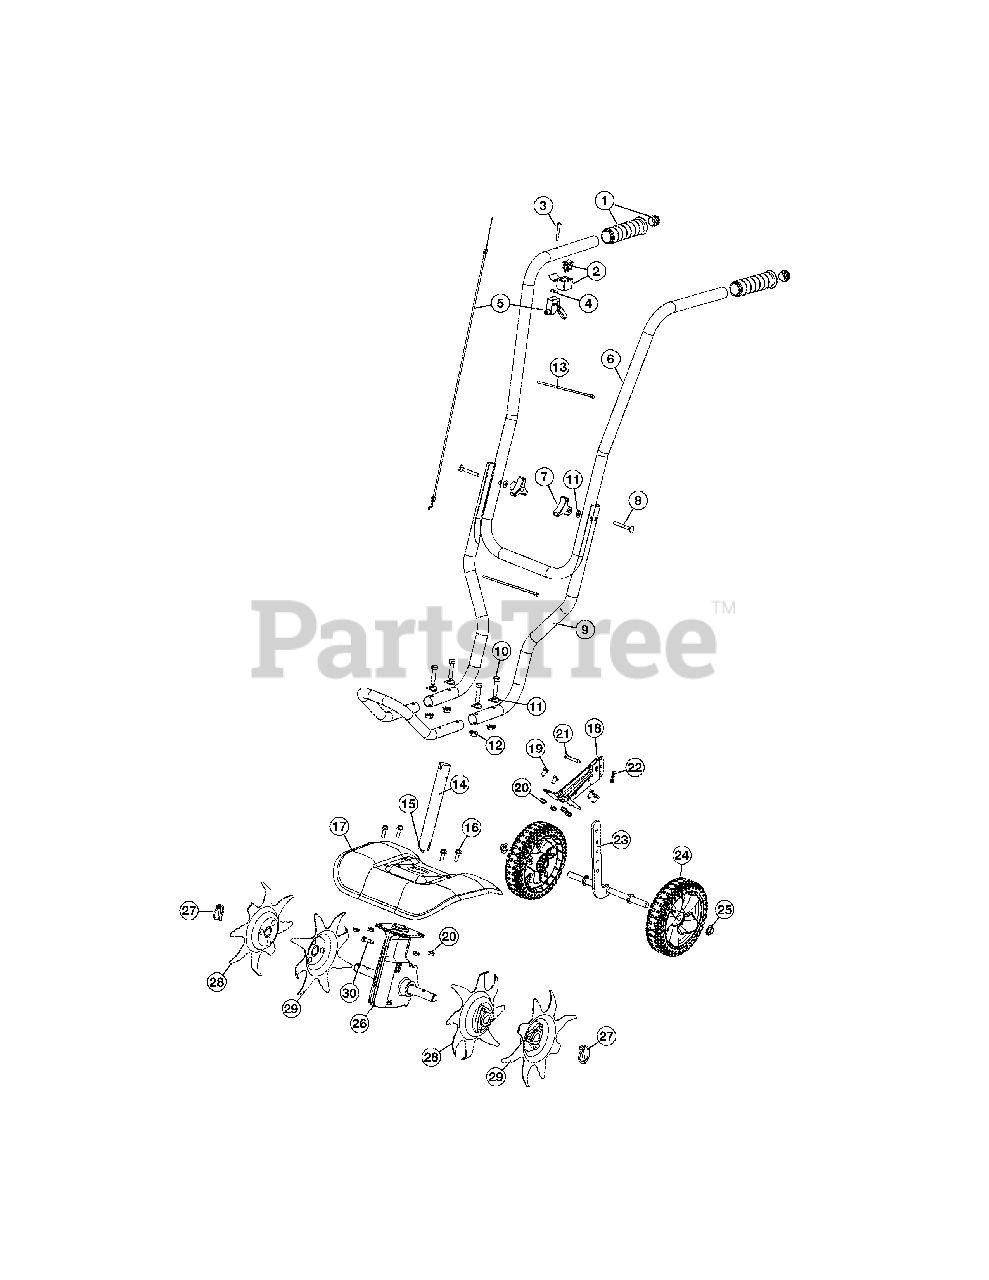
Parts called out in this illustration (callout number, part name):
2	Switch Assembly
3	Screw
4	Weld nut
5	Throttle Assembly
6	Upper Handle
9	Lower Handle Assembly
10	Bolt
11	Washer
12	Lock Nut
13	Cable Tie
14	Boom Assembly (Incl Ref No. 15)
15	Flex Shaft
16	Bolt
17	Tine Shield
18	Wheel Bracket Assembly
20	Lock Nut
21	Clevis Pin
22	Cotter Pin
23	Wheel Support Bracket
24	Wheel
25	Push Cap
26	Gearbox
27	Click Pin
28	RH Outer/ LH Inner Tine
29	RH Inner/ LH Outer Tine
30	Bolt
